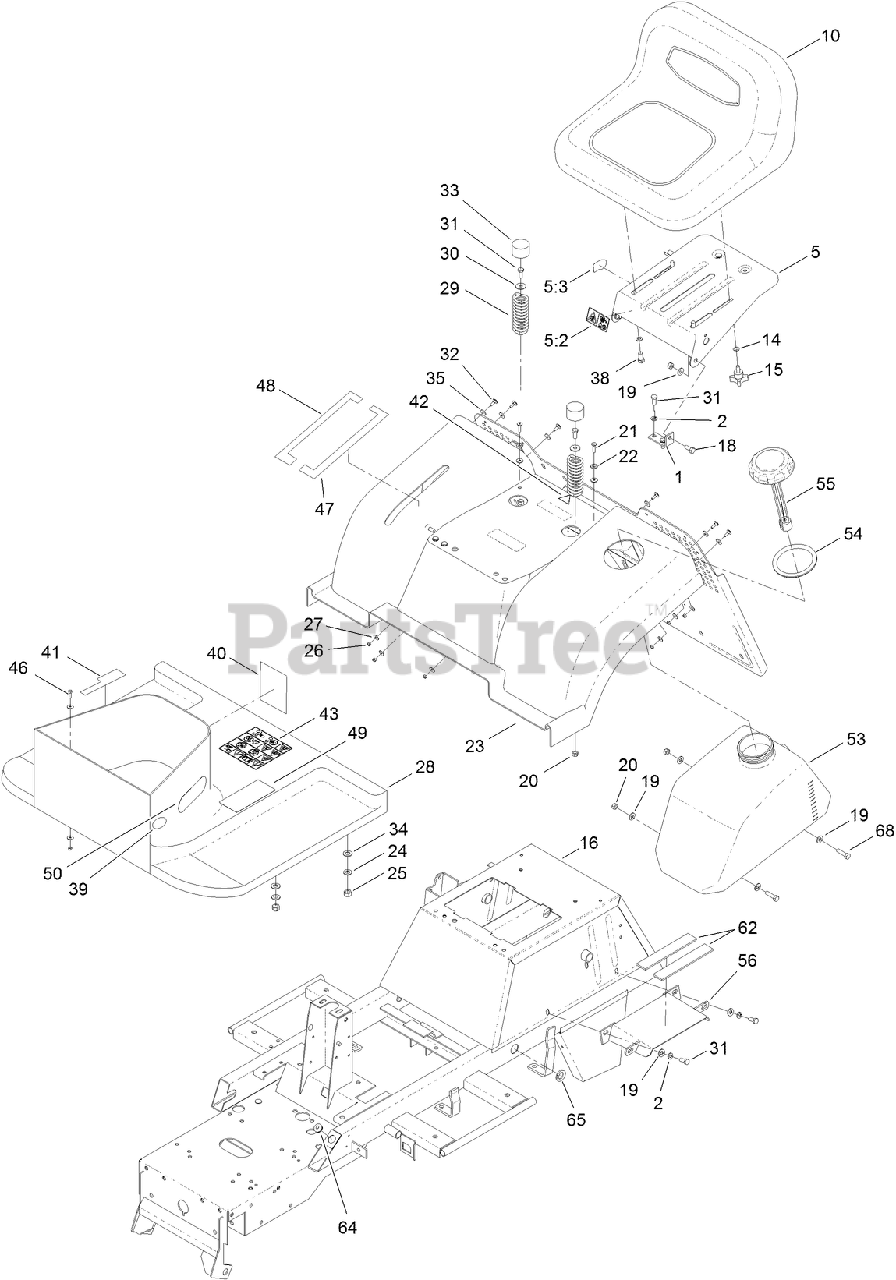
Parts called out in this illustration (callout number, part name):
1	BRACKET-SUPPORT, SEAT
2	WASHER-LOCK
5	SEAT PAN ASM
5:2	DECAL-DANGER
5:3	DECAL-SWITCH
10	SEAT ASM
14	WASHER-SPRING
15	KNOB-ADJUST
16	FRAME KIT
18	SCREW-SUPPORT, SEAT
19	WASHER-PLAIN
20	NUT-LOCK, NI
21	SCREW-HSFH
24	WASHER-FLAT
25	NUT-LOCK, NI
26	NUT-LOCK
27	WASHER-FLAT
28	FOOTREST ASM
29	SPRING-SEAT
30	WASHER-PLAIN
31	SCREW-HH
32	BOLT-CARRIAGE
33	CAP-HUB
34	WASHER-RUBBER
35	WASHER-RUBBER
38	SCREW-HHF
39	DECAL-BRAKE, PARKING
40	DECAL-STARTING
41	DECAL-OPERATION, HYDRO
42	DECAL-BAG TO FRAME
43	DECAL-DANGER
46	SCREW-HH
47	DECAL-HOC, LH
48	DECAL-HOC, RH
49	DECAL-OPERATION
50	DECAL-TOWER
53	TANK-FUEL
54	PROTECTOR-NECK, FILLER
55	CAP-FUEL
56	BRACKET-TANK, FUEL
62	STRIP-RUBBER, FUEL TANK
64	GROMMET
65	GROMMET
68	SCREW-HH
